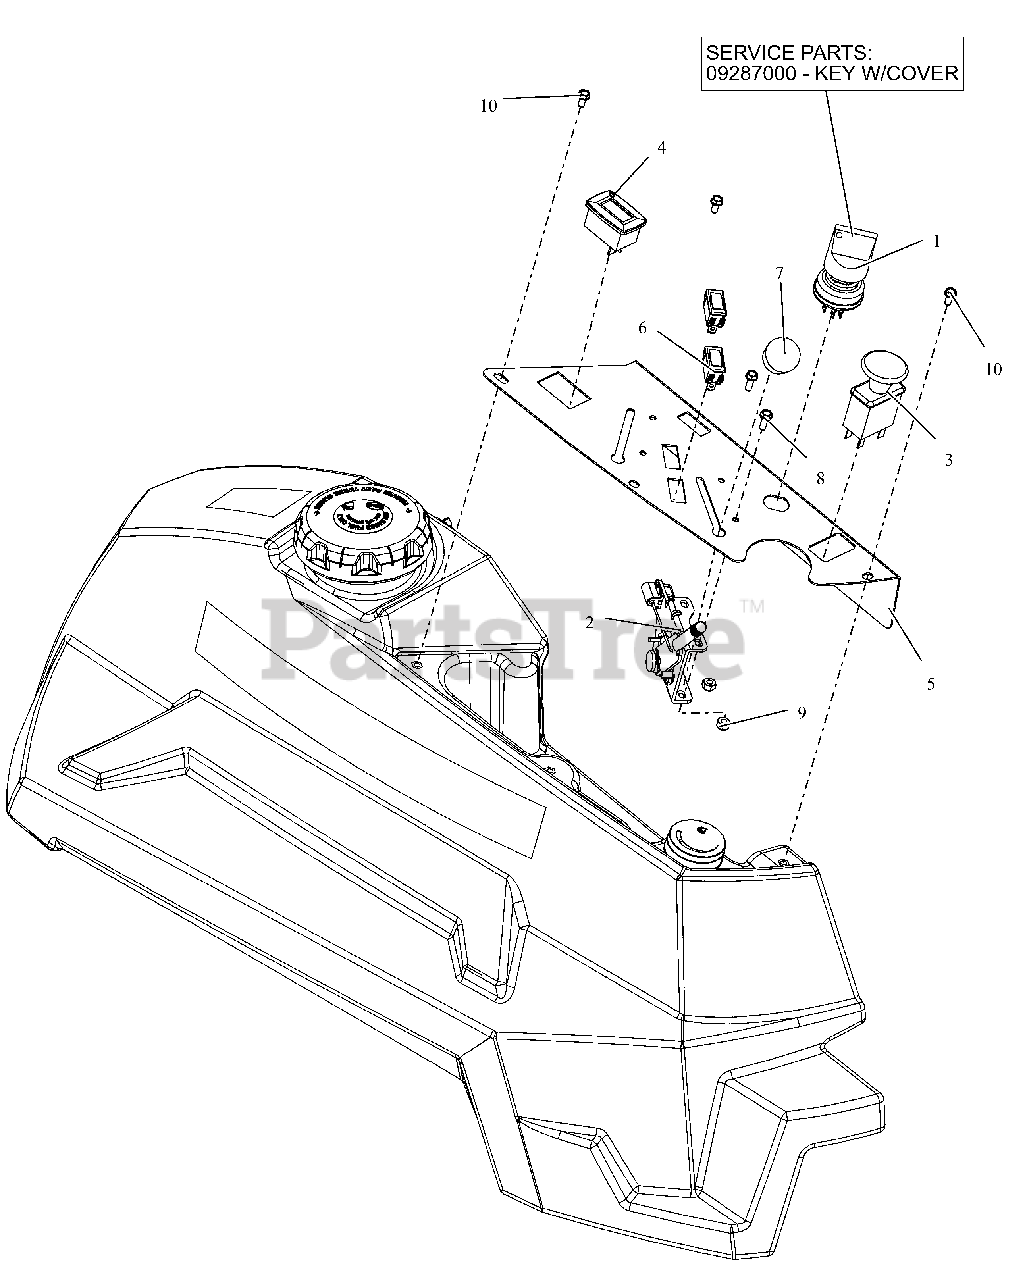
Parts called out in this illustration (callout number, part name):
1	SWITCH, IGNITION
1	KEY, W/ SHIELD
2	CABLE, PRO-CTRL 43.00"
3	SWITCH, CLUTCH
4	METER, HOUR W/MAINTENANCE
5	PT400 CONTROL PANEL - RED
6	LIGHT, INDICATOR (RED)
7	KNOB-CONTROL-BLACK .38-16X.50
8	BLT, HWH #10-24X.50 ZCC
9	NUT-LK-NYL #10-24 G2 ZCC
10	SCR-MCH 10-24X.38 HWHSTAINLESS
